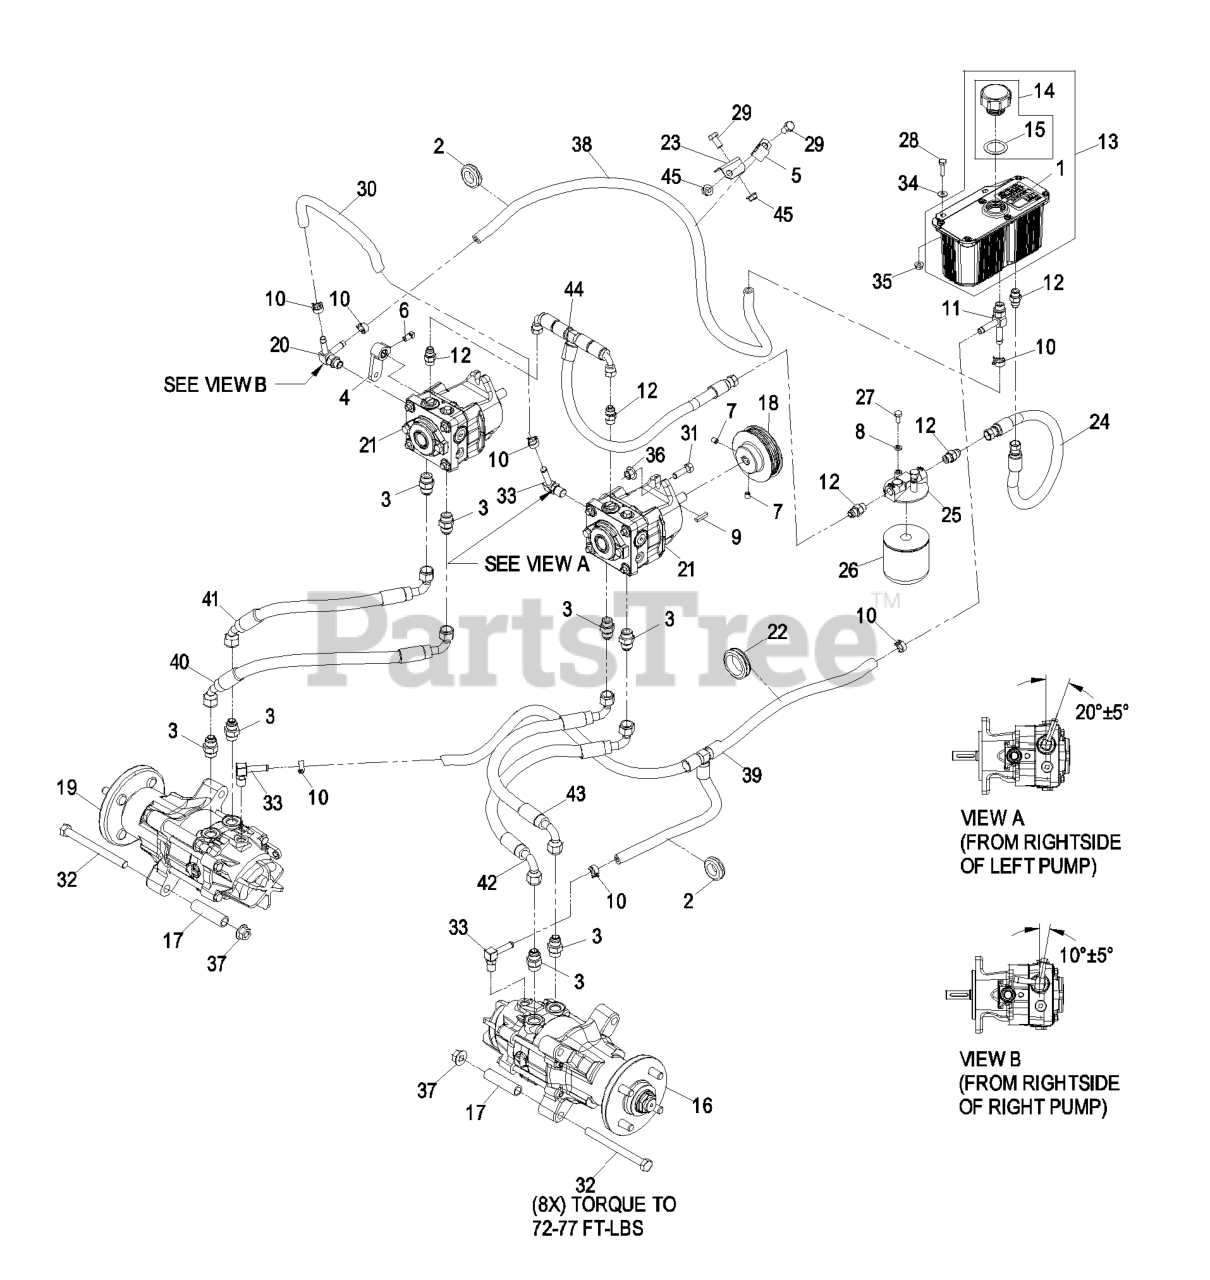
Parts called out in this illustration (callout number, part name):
1	DECAL-HYDRAULIC TANK
2	GROMMET
3	FITTING-STRAIGHT
4	ARM-CONTROL, PUMP
5	CLIP-LOOM
6	SCREW-SET
7	SCREW-SET
8	WASHER-LOCK
10	CLAMP-HOSE
11	ADAPTER-RUN, TEE
12	FITTING-STRAIGHT
13	HYD RESERVOIR ASM
14	KIT,HYD RES CAP W/GASKET
15	GASKET-CAP
16	MOTOR,PRM18-LH
19	MOTOR,PRM18-RH
20	ADAPTER-TEE
22	GROMMET
23	BRACKET-CLAMP
24	HYDRAULIC HOSE ASM
25	HEAD-FILTER
26	FILTER-25 MICRON, BI-DIRE
27	SCREW-HH
28	SCREW-HH
29	SCREW-HH
30	HOSE-HYD
31	SCREW-HH
32	SCREW-HH
33	FITTING-ELBOW, 90
34	WASHER-FLAT
36	NUT-FLANGE
37	NUT-HHF
38	HOSE-HYD
39	ASM,HYDRAULIC HOSE
40	ASM,HYDRAULIC HOSE
41	ASM,HYDRAULIC HOSE
42	ASM,HYDRAULIC HOSE
43	ASM,HYDRAULIC HOSE
44	HYDRAULIC HOSE ASM
45	NUT-HHF, WHIZ
